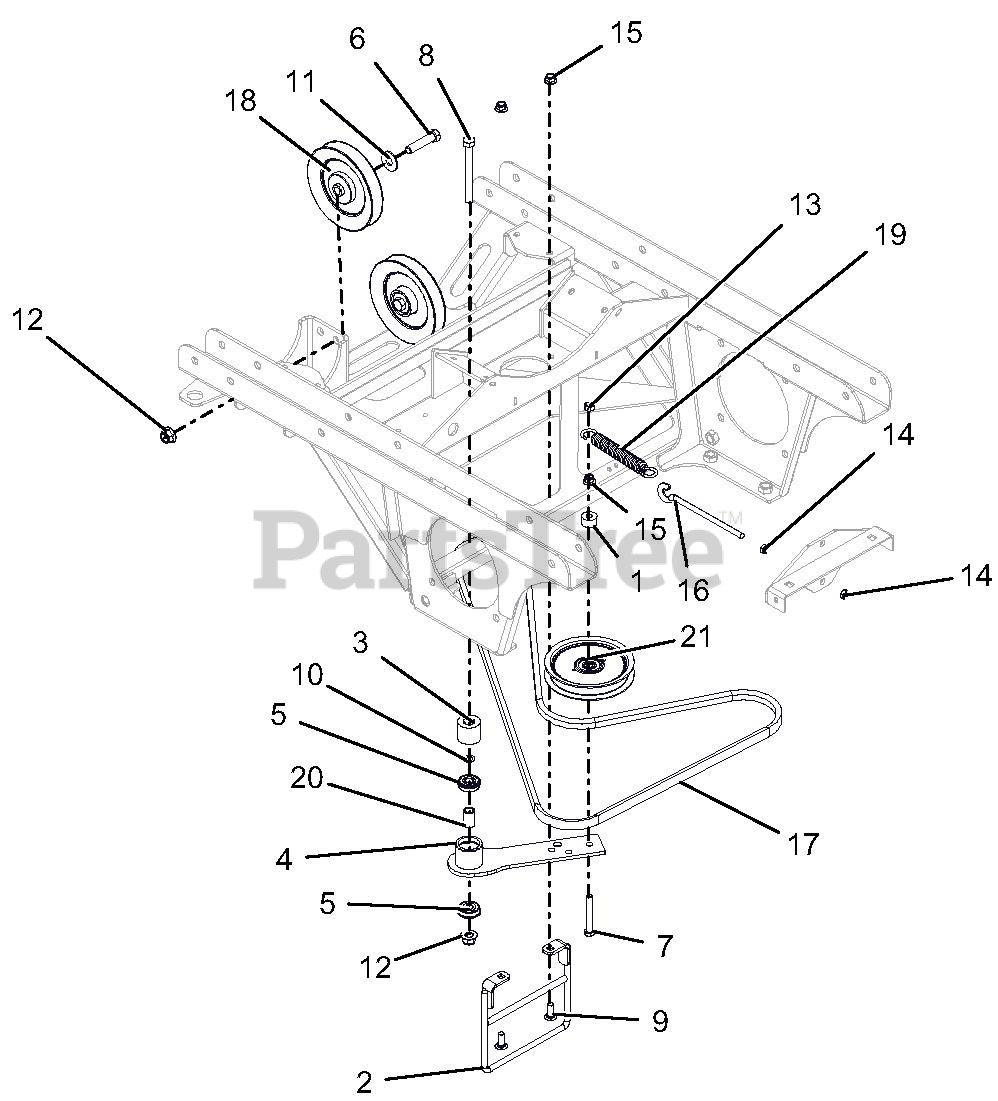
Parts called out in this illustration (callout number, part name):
1	SPACER .390X1.000X.562
2	WLDMT, DIESEL BELT FINGER
3	SPCR, PT400 DIESEL IDLER ARM
4	WLDMT, HYDRO DRIVE IDLER ARM
5	BRG, BALL .501 X 1.38 X .438 SEALED
6	BLT-HEX .50-13X2.25 GR5 YWZC
7	BLT-HEX .38-16X2.75 GR5 YWZC
8	BLT-HEX .50-13X4.50 GR5 YWZC
9	BLT-RDHDSHSQNK.38-16X1.0 G5YZ
10	WASHER-FLAT-STL, .500 X .750 X .020
11	WSHR-FL-STL.563X1.38X.109YWZC
12	NUT-LK-NYL-FLG .50-13 YWZC
13	NUT-LK-CTR .38-16 YWZC
14	NUT, JAM .375-16 YWZC
15	NUT-LK-NYL-FLG .38-16 YWZC
16	BOLT, .38-16X6.00 .62 DIA EYE
17	BELT, 5L RAW EDGE
18	PULLEY, V-IDLER 6.0X.500 ID DBL BRG
19	SPRG, EXTENSION
20	SPACER, .510 X .750 X 1.148
21	IDLER, FLAT - 5.00" X .75"
